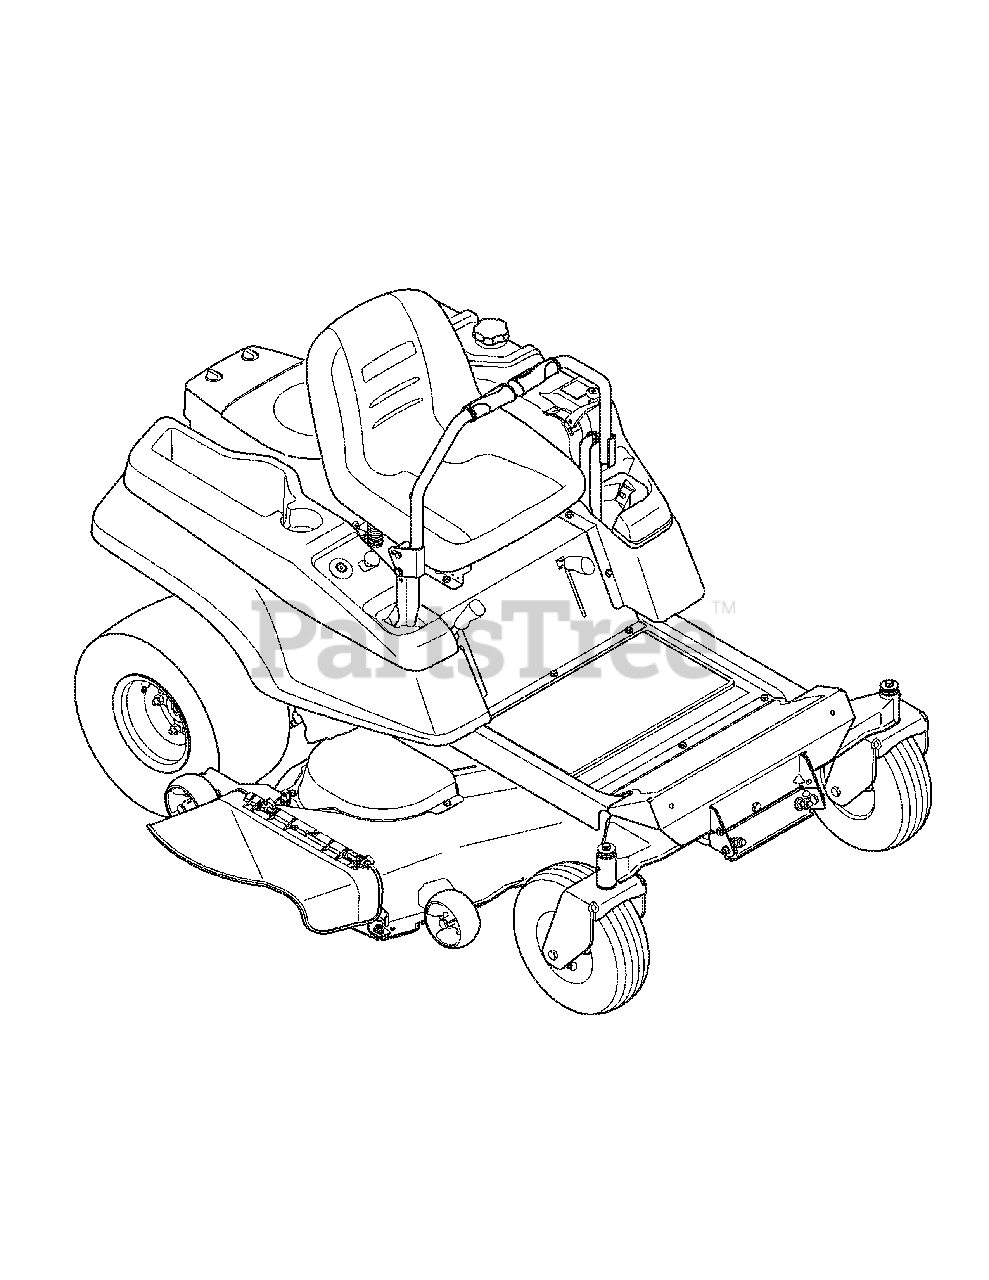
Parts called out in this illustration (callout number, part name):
NA	PRE-CLEANER ELEMENT
NA	UPPER DRIVE BELT
NA	ENGINE TO DECK BELT
NA	BALL JOINTS
